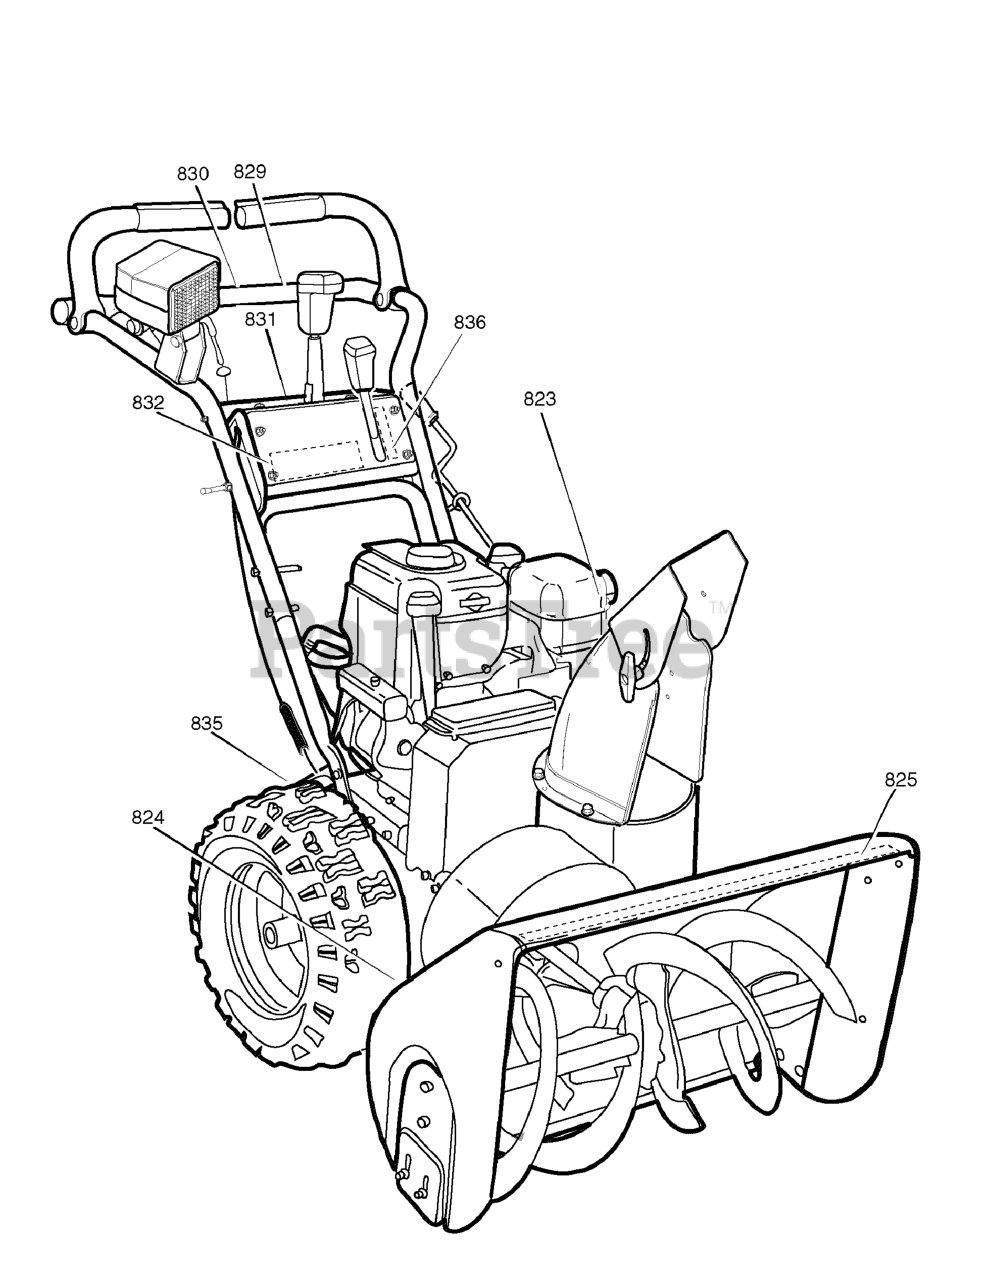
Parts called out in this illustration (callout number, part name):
823	DECAL, DANGER CHUTE HAND
824	DECAL, DANGER FOOT
825	DECAL, CRAFTSMAN 1350/27
829	DECAL, DRIVE CLUTCH
830	DECAL, AUGER CLUTCH
831	DECAL, GEAR SELECTOR
832	DECAL, CRAFTSMAN
835	DECAL, ID PLATE
836	DECAL, REMOTE CHUTE FR/ENG
